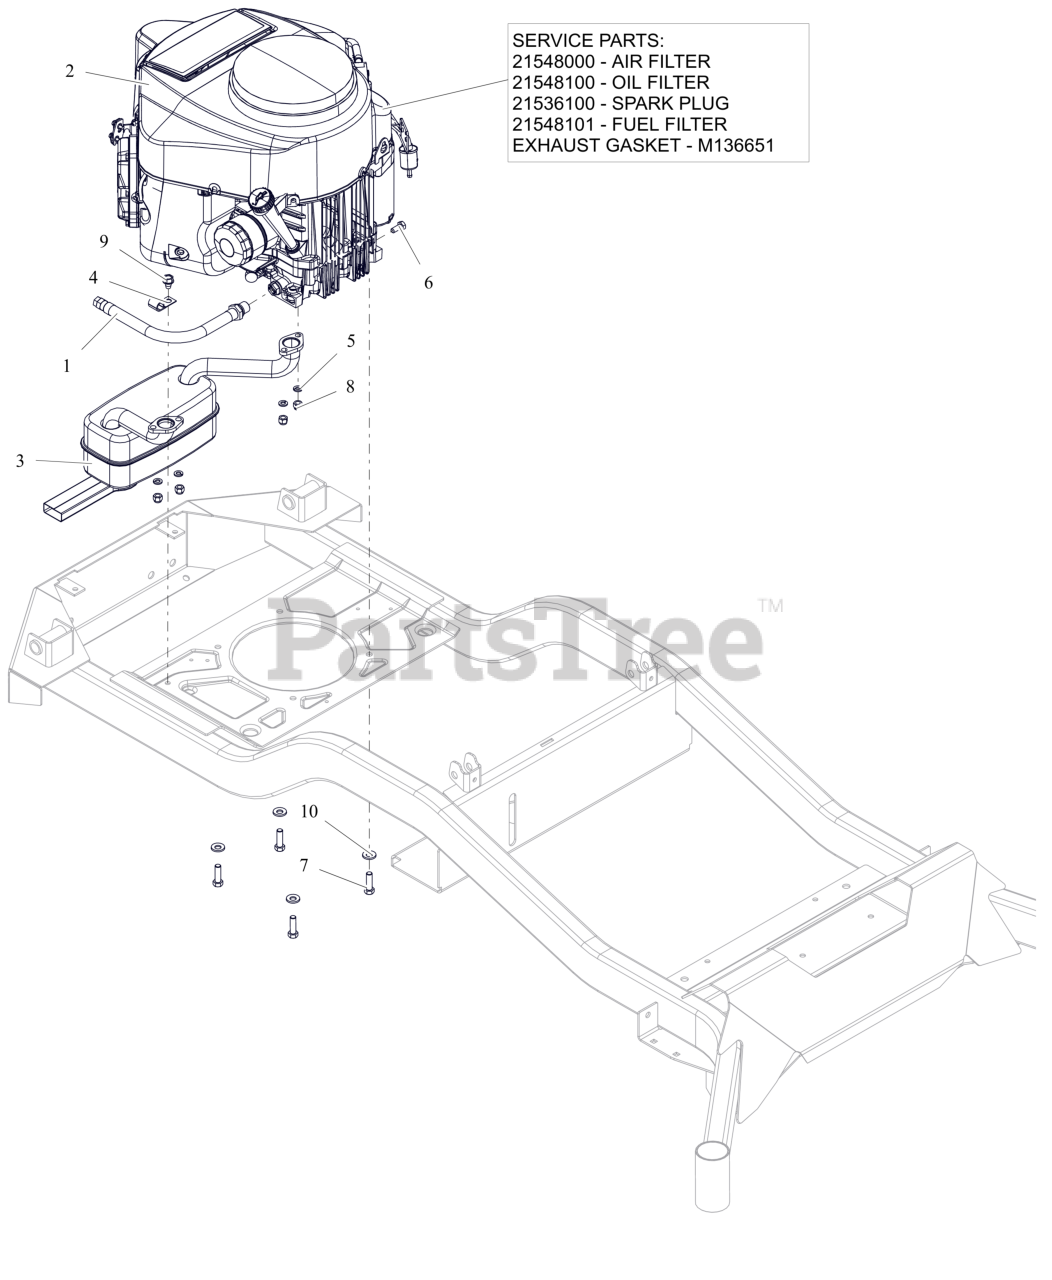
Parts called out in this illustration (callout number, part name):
1	HOSE, OIL DRAIN
1	AIR FILTER, KAWASAKI FR
1	OIL FILTER, KAWASAKI FR
1	PLUG, SPARK
1	FUEL FILTER-KAWASAKI FR
1	GASKET, MUFFLER #
2	ENGINE, KAWASAKI FR730 24HP
3	MUFFLER, KAWASAKI
4	J-CLAMP
5	WSHR,LK-REG .312X.078 ZCC
6	BLT, HEX M8-1.25X20 G8.8 ZCC
7	BLT, HEX .38-16X1.25 G5 ZCC NT
8	NUT, LK-CTR-JAM M8-1.25 GR8.8 ZC120
9	SCR,TAP .375-16X.50 HWH TR ZCC
10	WASHER, 3/8" SPRING DISC
